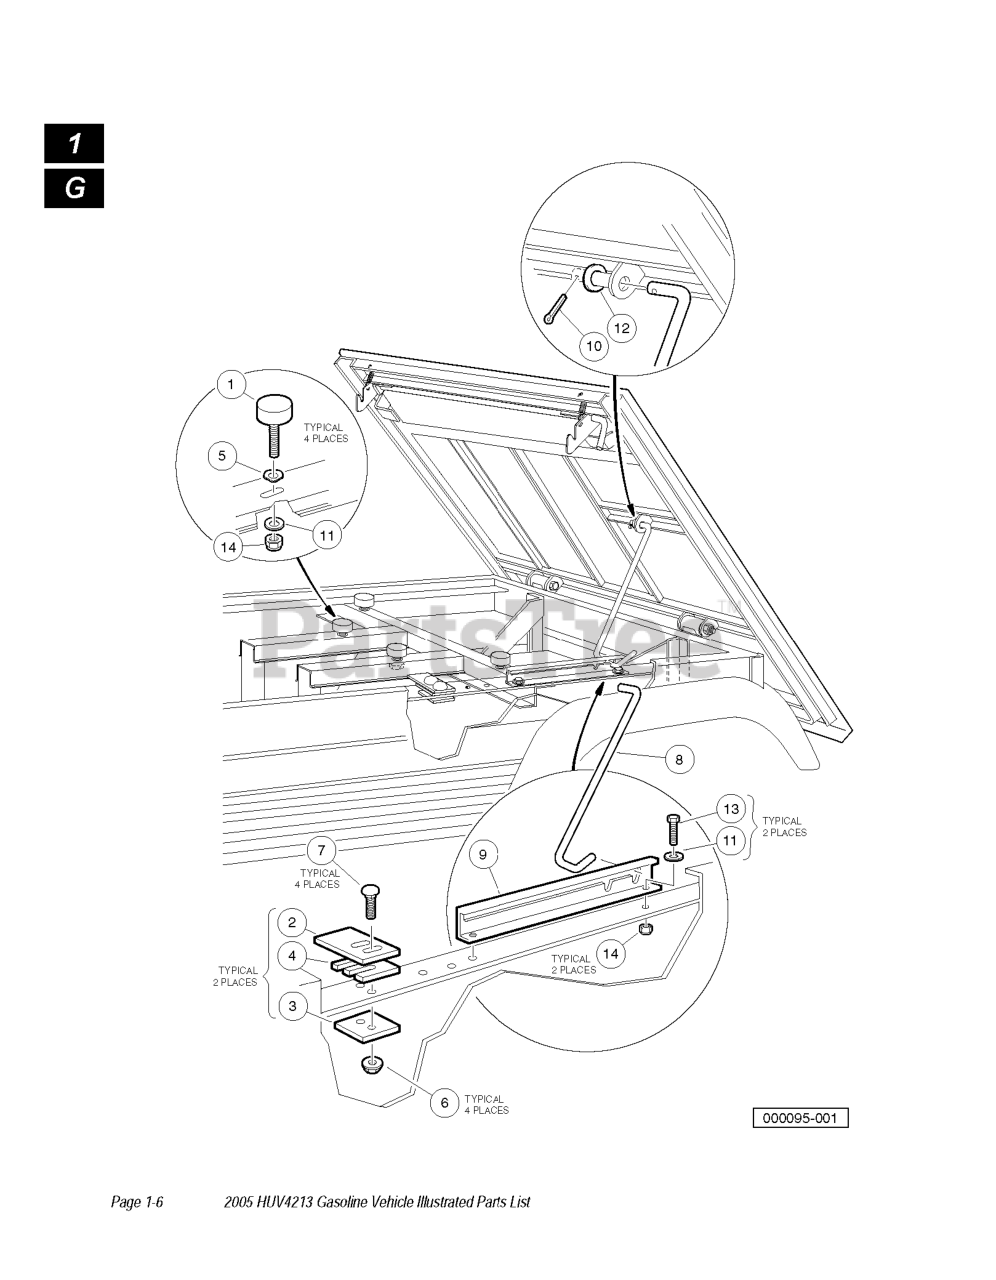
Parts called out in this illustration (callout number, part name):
1	BUMPER, BRAKE PEDAL RUBBER
2	LATCH PLATE
3	PLATE, LATCH SUPPORT
4	LATCH PLATE SHIM
5	WASHER, WAVE
6	LOCKNUT, 1/4-20 HEX WHIZ
7	BOLT, 1/4-20 X 1.0 RD HD SQ NK
9	TRACK, PROP ROD
10	PIN,CUT COTTER
11	WASHER 1/4 FLAT
12	WASHER, 3/8 FLAT
13	SCREW, 1/4-20 X .75 HEX
14	LOCKNUT, 1/4-20 NYLON INSERT
